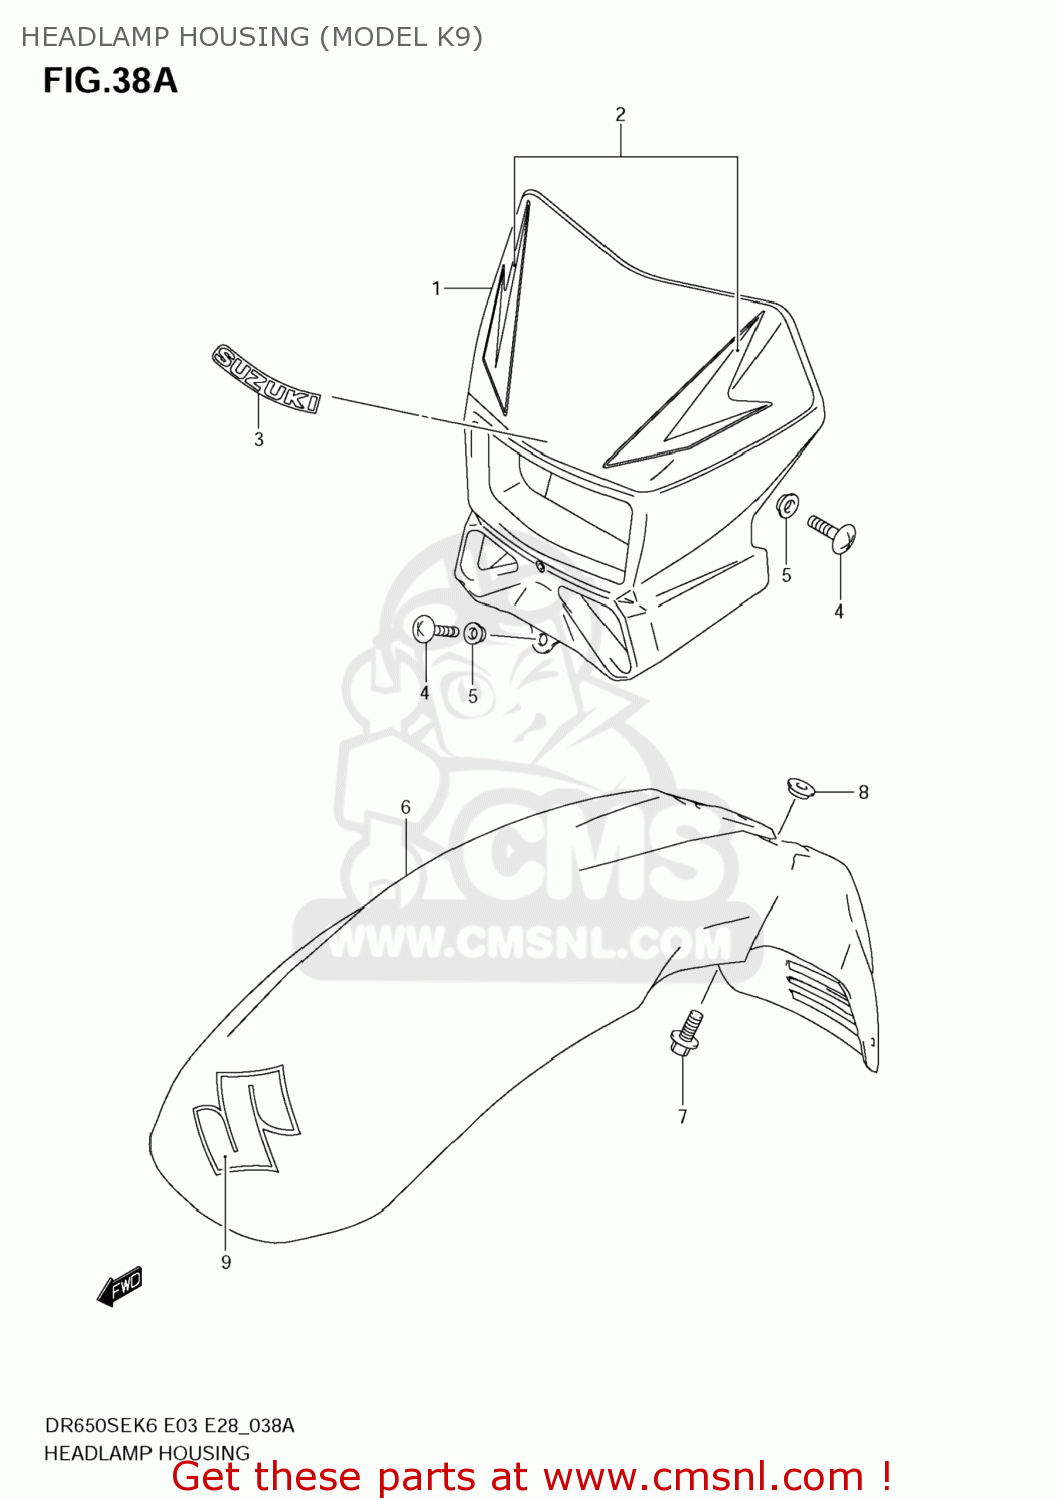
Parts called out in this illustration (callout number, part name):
1	COVER,HEADLAMP
2	TAPE SET,HEADLAMP HOUSING
3	EMBLEM,SUZUKI
4	SCREW
5	WASHER
6	FENDER,FR
7	BOLT(6X16)
8	WASHER
9	EMBLEM,S
